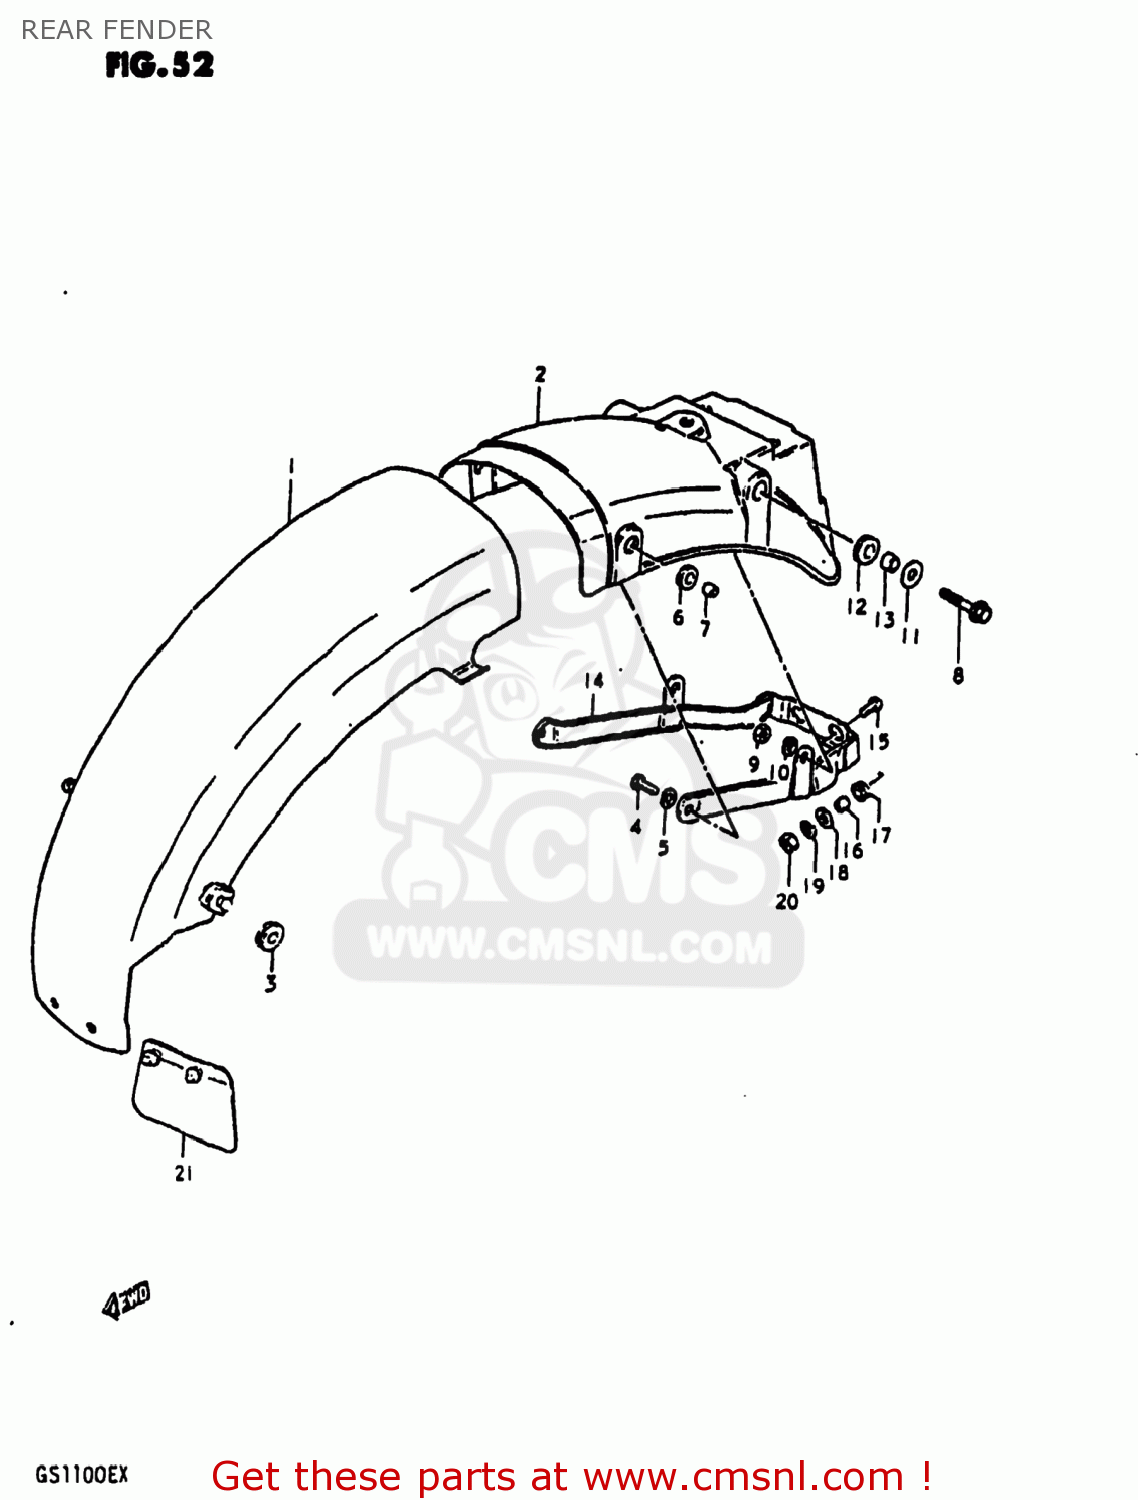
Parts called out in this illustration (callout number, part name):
1	FENDER,REAR
2	BODY,REAR FENDER,REAR
3	CUSHION
4	BOLT
5	LOCK WASHER
6	CUSHION
7	SPACER(6.1X9X7.5)
8	BOLT
9	NUT
10	LOCK WASHER
11	WASHER(8.5X26X1.2)
12	CUSHION
13	SPACER (8.2X12X7.5)
14	REINFORCEMENT,REAR FENDER
15	SCREW
16	SPACER (6.1X9X9)
17	CUSHION
18	WASHER(6,5X22X1.6)
19	LOCK WASHER
20	NUT
21	GUIDE,RR FENDER MUD
